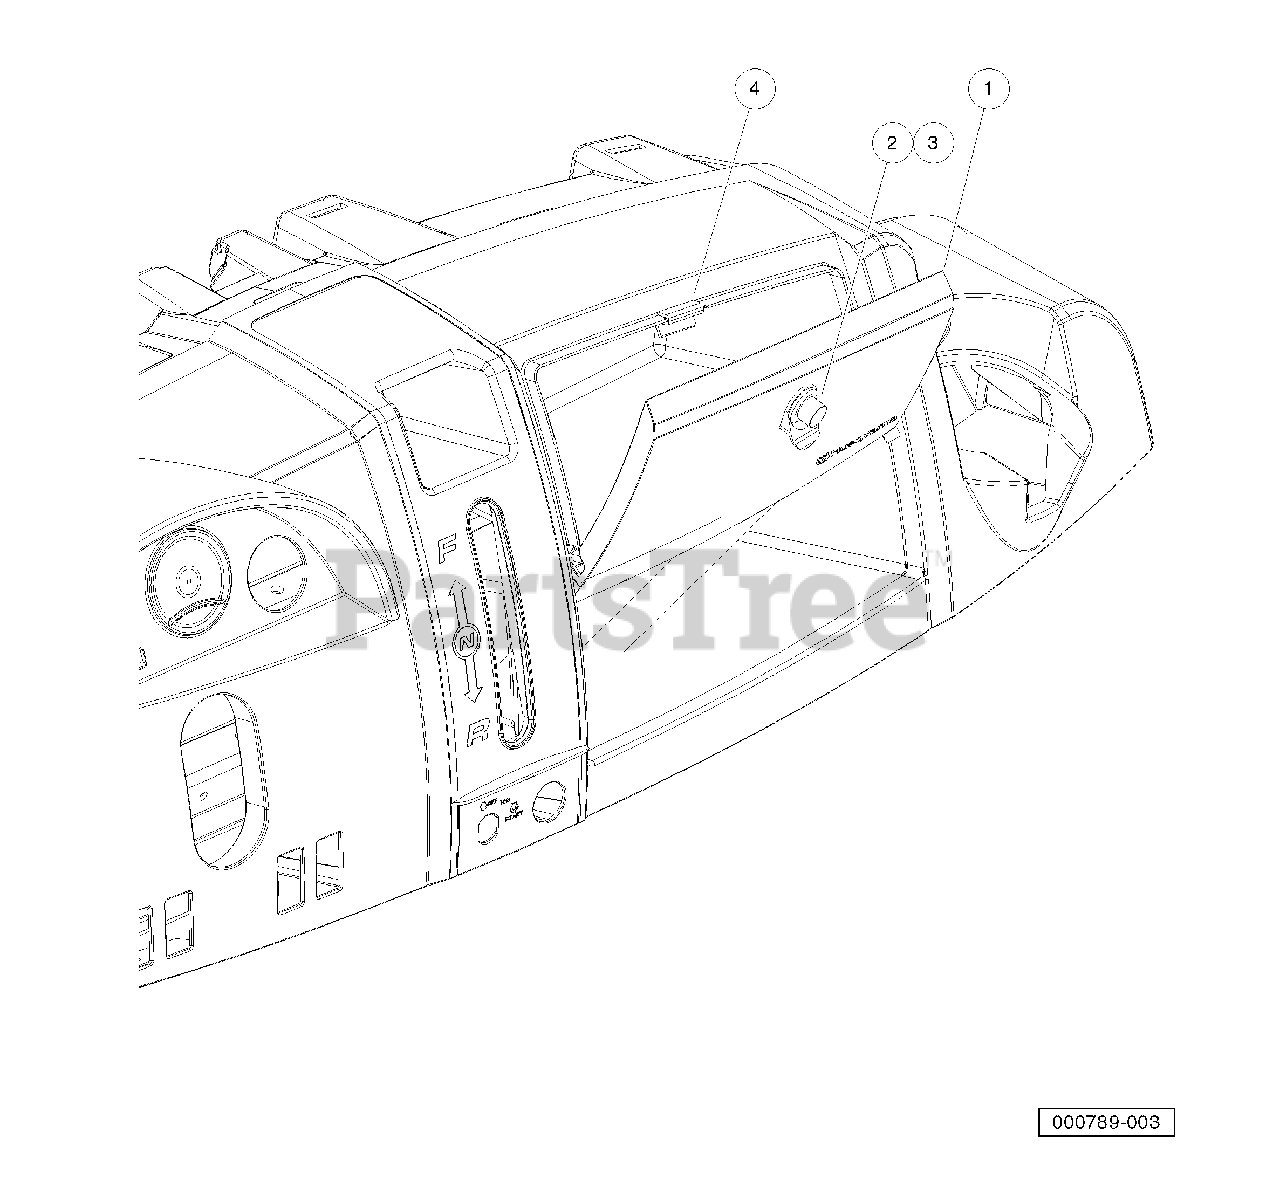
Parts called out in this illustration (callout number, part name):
1	Cover, Storage, Dash, Awd, Cci
2	Latch, Push Close
3	Latch, Push Close W/ Key
4	Keeper, Latch, Push Close
